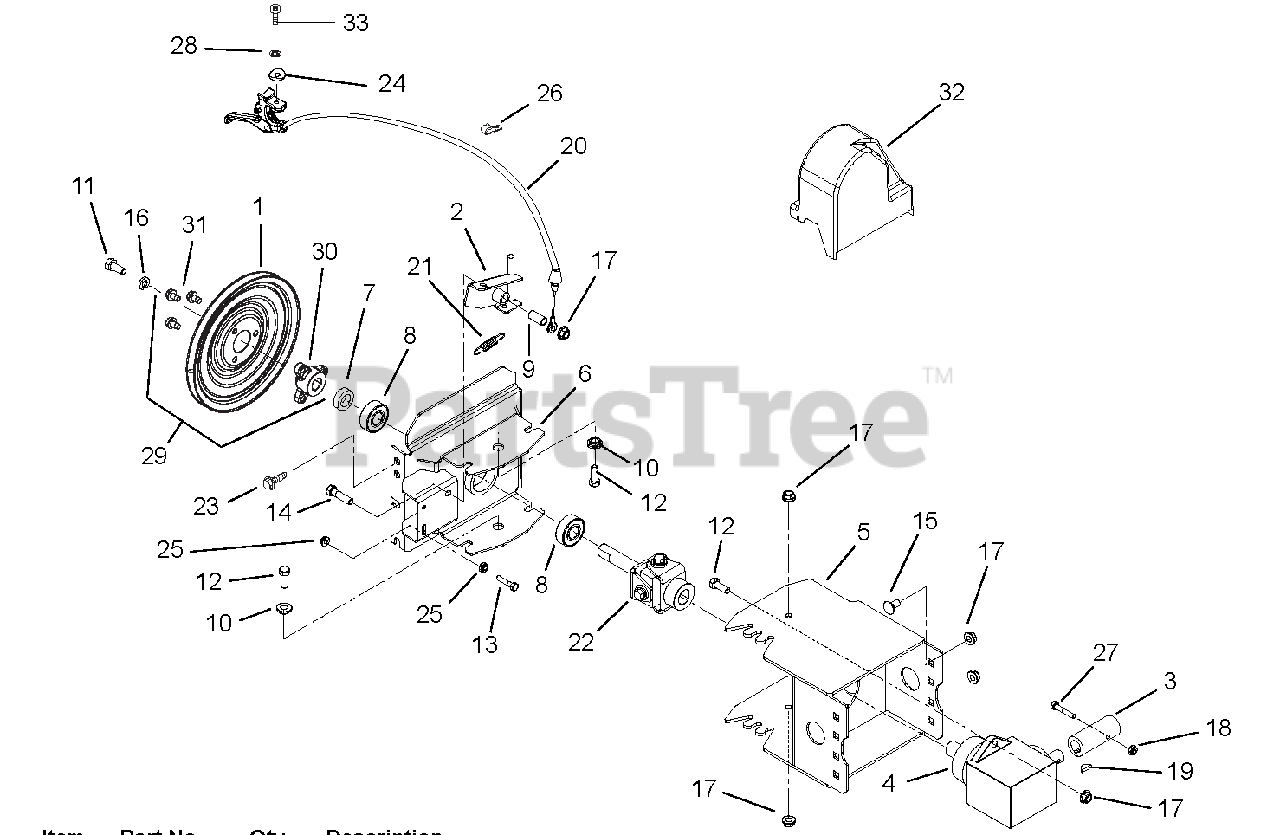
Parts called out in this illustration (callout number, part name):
1	PULLEY,SPIN FORM SINGLE GROOVE
2	ARM, PIVOT LOCK
3	HUB, COUPLING
4	GEAR BOX ASSEMBLY
5	ADAPTER WITH DECAL,BRUSH FRAME
6	ADAPTER, FRAME-20000 SERIES
7	SPACER .755X1.250X.370
8	BRG-BALL .750X1.781X.61
9	BSHG-SLV .385X.500X1.045
10	BSHG-FLG .406X.88X.270X.140
11	BLT-HEX .31-24X.75 YWZC GR5
12	@BLT-HEX .38-16X1.00 GR5 YWZC
13	@BLT-HEX .25-20X1.50 GR5 YWZC
14	@BLT-HEX .38-16X1.75 GR5 YWZC
15	@BLT-RDHDSQNK .38-16X.75 G5YZ
16	WSHR-LK .312X.097 HVY YWZC
17	@NUT-LK-TOP-FLG .38-16 YWZC
18	@NUT-LK-TOP-FLG .25-20 YWZC
19	KEY-WDRF .188X.75X.313 SAE 9
20	CABLE, REMOTE BRUSH LOCK
21	SG-TENS .06X.46X2.00
22	U-JOINT ASSY
23	@SCR-TAP .31-18X.75 HWH TR YWZ
24	SPACER, HANDLEBAR
25	@NUT-SPNLK-FLG .25-20 YWZC
26	J-CLAMP
27	@BLT-HEX .25-20X1.75 GR5 YWZC
28	WSHR-LK-INT .250 TH TYA
29	PULLEY WITH HUB
30	PULLEY HUB, BOLT-ON D-BORE .75
31	@SCR-TAP .31-18X.50 HWH TR YWZ
32	BELT COVER
33	SCR-MCH .25-20X1.50 OVAL HD
